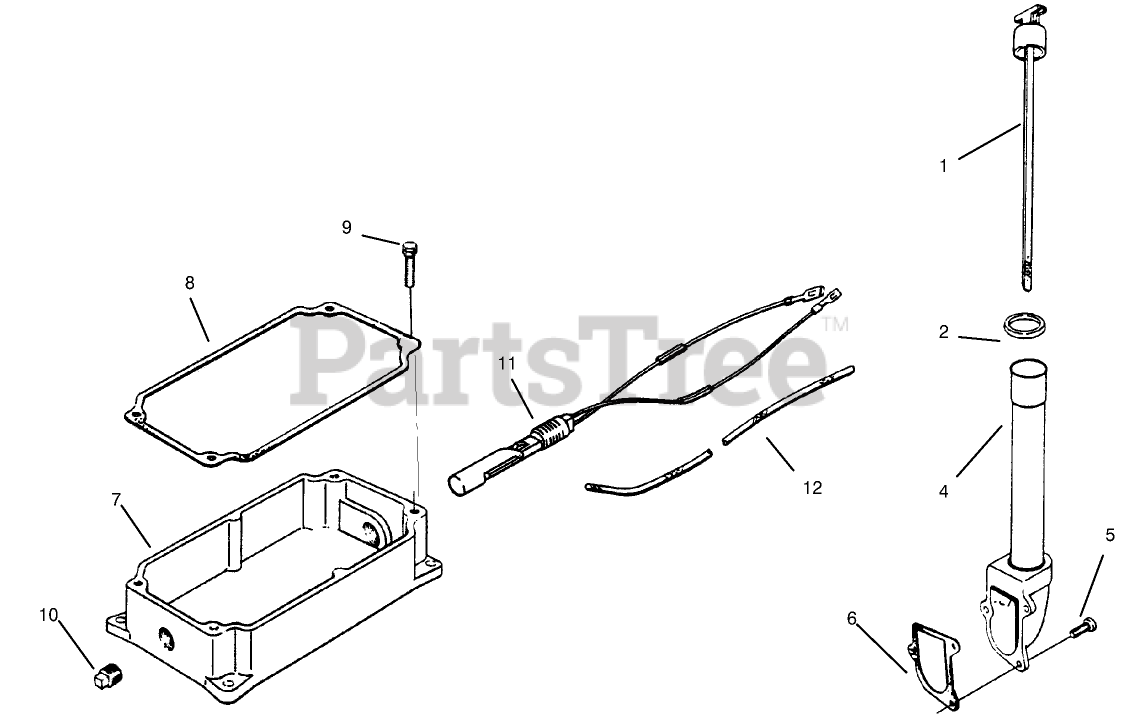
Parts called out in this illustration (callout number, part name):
1	Dipstick
2	O-Ring
4	Adapter-Oil Fill
5	Screw
6	Gasket
7	Pan-Oil
8	Gasket
9	Screw
10	Plug
11	Kit-Float Switch
12	Sleeve
